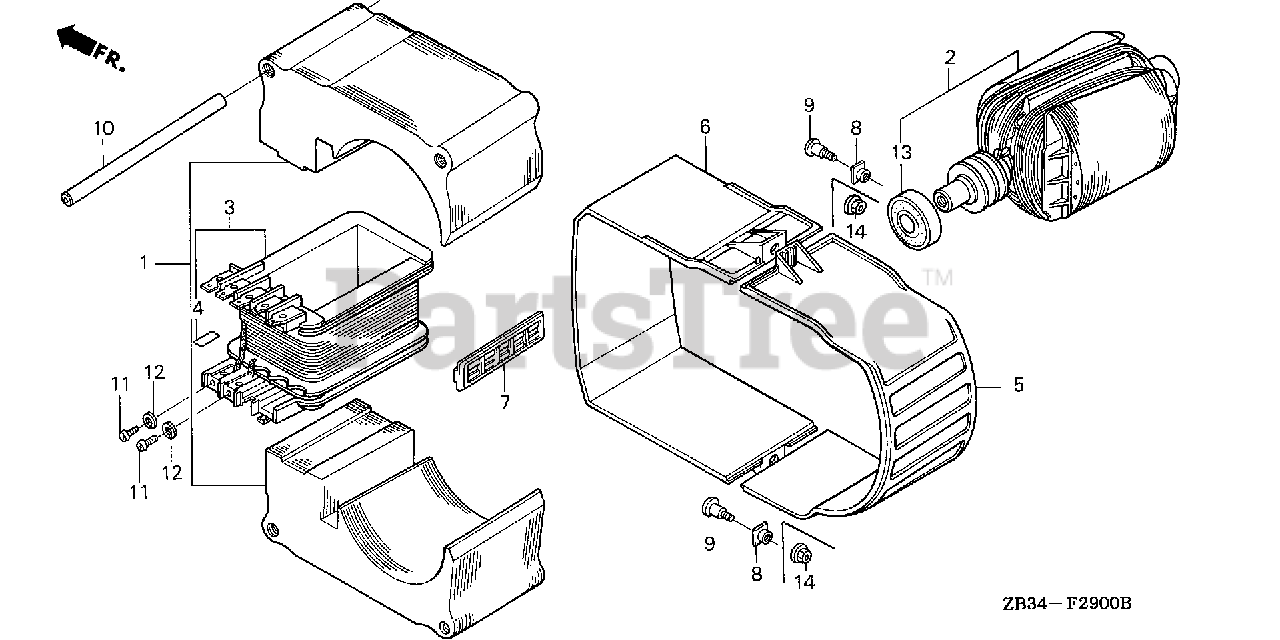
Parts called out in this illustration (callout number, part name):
1	CORE SET, STATOR
3	BOBBIN, STATOR COIL (NOT AVAILABLE)
3	BOBBIN, STATOR COIL
4	MARK, WIRE COLOR
5	COVER, R. STATOR
6	COVER, L. STATOR
9	BOLT, STATOR COVER SETTING
10	PIN, DOWEL (11X131)
11	SCREW, PAN (5X8)
12	WASHER, SPRING (5MM)
13	BEARING ASSY. (6203)
14	NUT, FLANGE (5MM)
